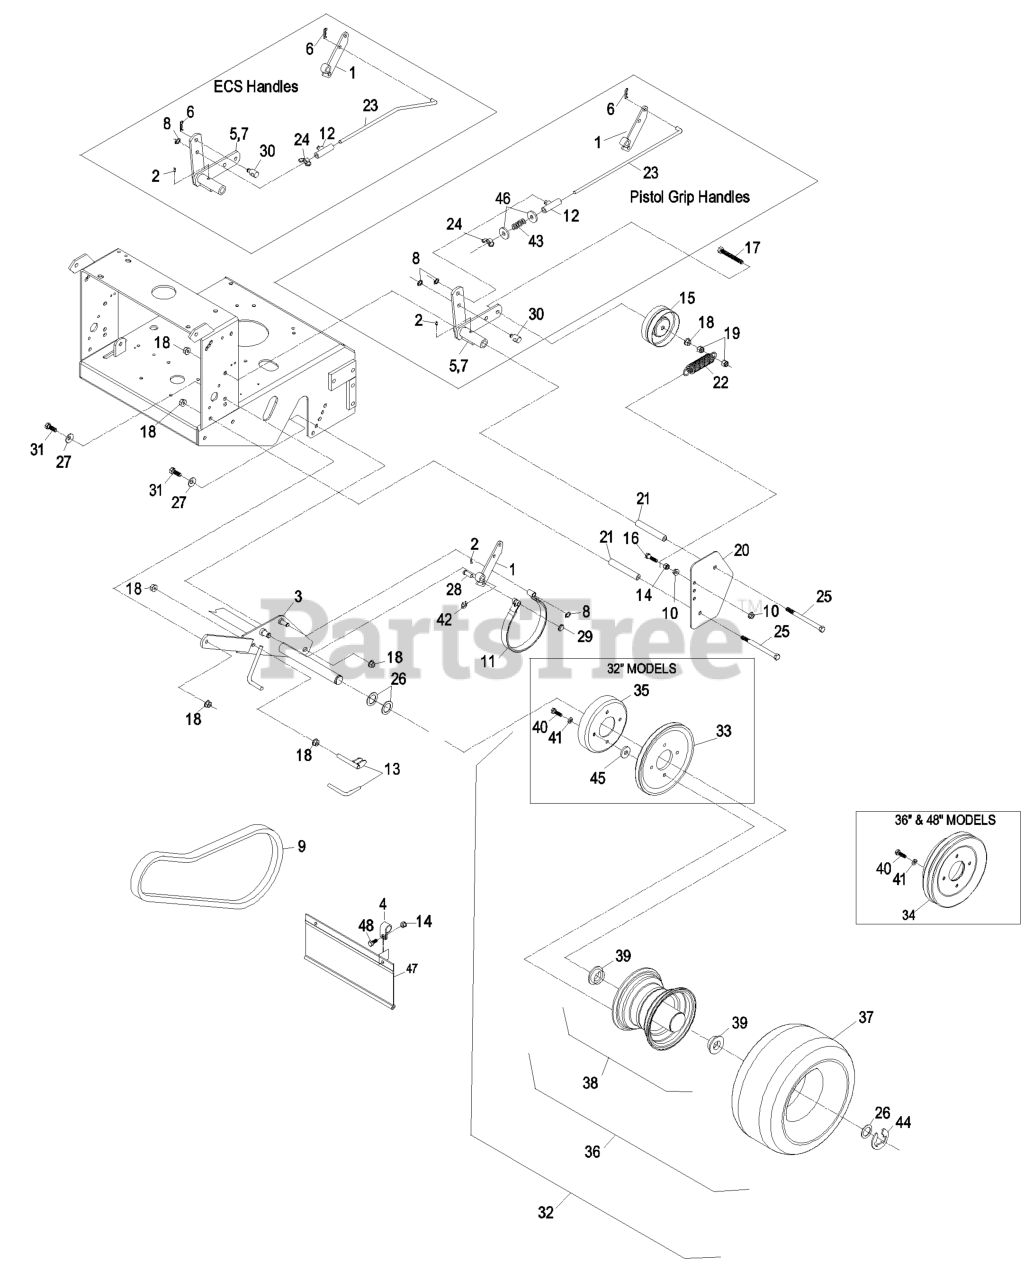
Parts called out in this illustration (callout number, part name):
1	ARM-BRAKE
2	FITTING-GREASE
3	AXLE
4	CLAMP-R
6	PIN-COTTER
8	RING-RETAINING
9	BELT,WHEEL DRIVE
11	BAND-BRAKE
12	SWIVEL-BRAKE
13	SCRAPER
14	NUT-LOCK, NI
15	IDLER-WHEEL, DRIVE
16	SCREW-HH
17	SCREW-HH
18	NUT-HHF, WHIZ
19	NUT-LOCK, NI
20	SHIELD-WHEEL, DRIVE
21	SPACER-SHIELD
22	SPRING-EXTENSION
23	LINKAGE-BRAKE
24	WINGNUT-NYLOCK
25	SCREW-HH
26	WASHER-SPACER
27	WASHER-BELLEVILLE
28	PIN-CLEVIS
29	RING-RETAIN,PUSH,EXT,FLAT
30	SWIVEL-LEVER, DRIVE
31	SCREW-HH
32	DRIVE WHEEL ASM
33	SHEAVE-WHEEL, DRIVE
34	DRUM AND SHEAVE ASM
35	DRUM-BRAKE
36	WHEEL AND TIRE ASM
37	TIRE-TURFMASTER
38	WHEEL AND HUB ASM
39	BEARING-FLANGED
40	SCREW-HH
41	WASHER-LOCK
42	RING-RETAINING, EXTERNAL
43	SPRING-COMPRESSION
44	RING-SNAP
45	WASHER
46	WASHER-PLAIN
47	SHIELD-TRAILING
48	SCREW-HH
